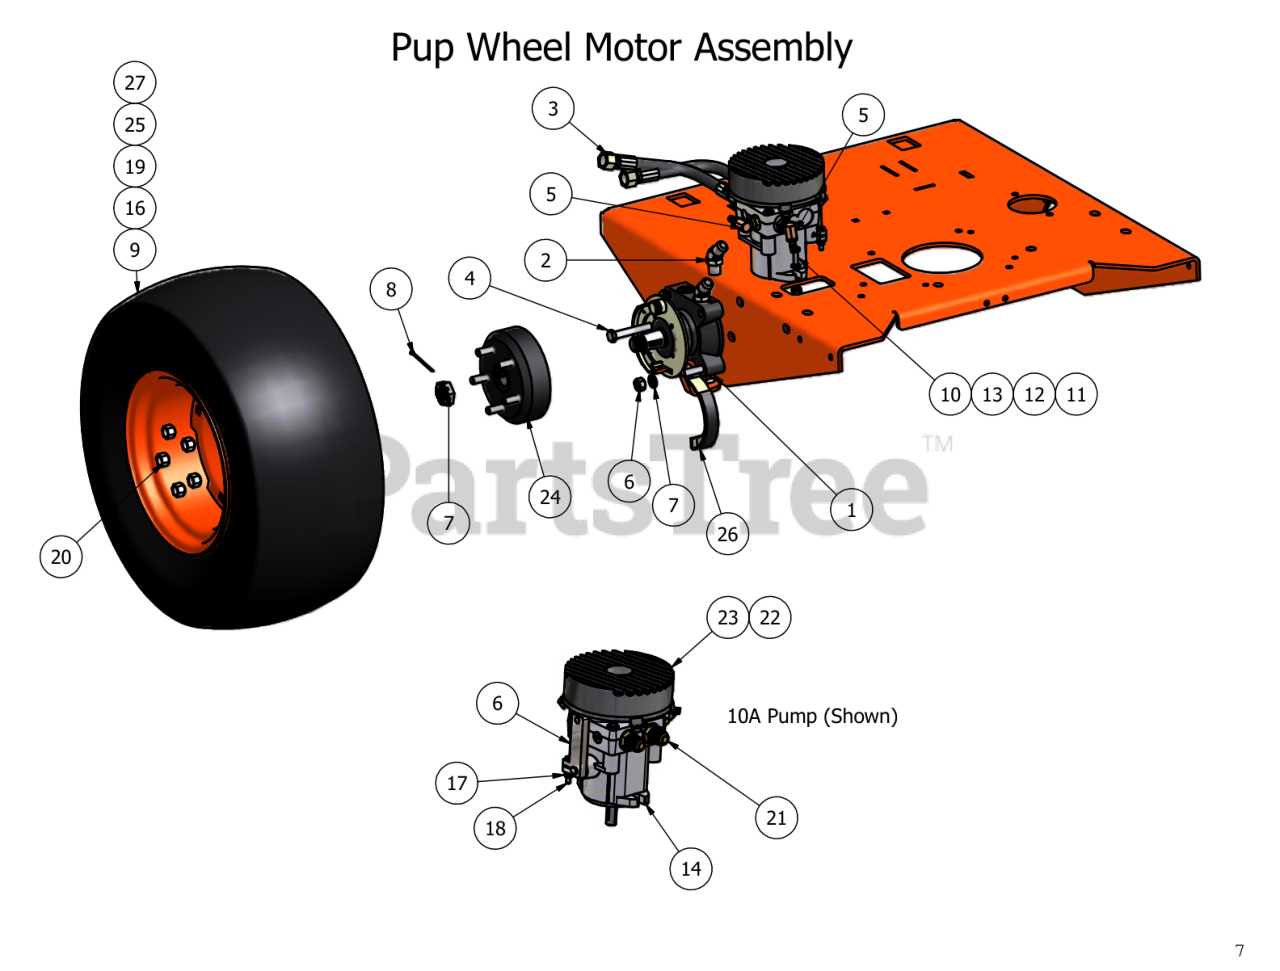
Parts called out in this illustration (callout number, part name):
1	Brake & Wheel Motor (Right)
1	Brake & Wheel Motor (Left)
2	HYdraulic Fitting (Wheel Motor)
3	Hydraulic Hose
4	1/2" x 3" Hex Bolt
5	3/8" x 9/16" Male Fitting
6	Pup Pump Arm
7	Castle Nut
8	1/8" x 2 1/4" Cotter Pin
9	12" Rim -60"&72" Cut
10	3/8" x 1 1/2" Hex Bolt
11	3/8" Hex Nut
12	3/8" Lock Washer
13	3/8" Flat Washer
14	Hydraulic Pump (10A) Left
15	Hydraulic Pump (10A) Right
16	24 x 12-12 Tire 60"&72" Cut
17	1/4" Nylock Nut
18	1/4" x 1 1/2" Bolt Straight Thread
19	24" Tire and Wheel Assembly
21	Hydraulic Fitting
22	Hydraulis Fan
24	Brake Drum
25	23 x 10.50-12 Tire & Wheel
26	Brake Pads
27	12" Rim 48"&52" Cut
28	23 x 10.50-12 Tire
